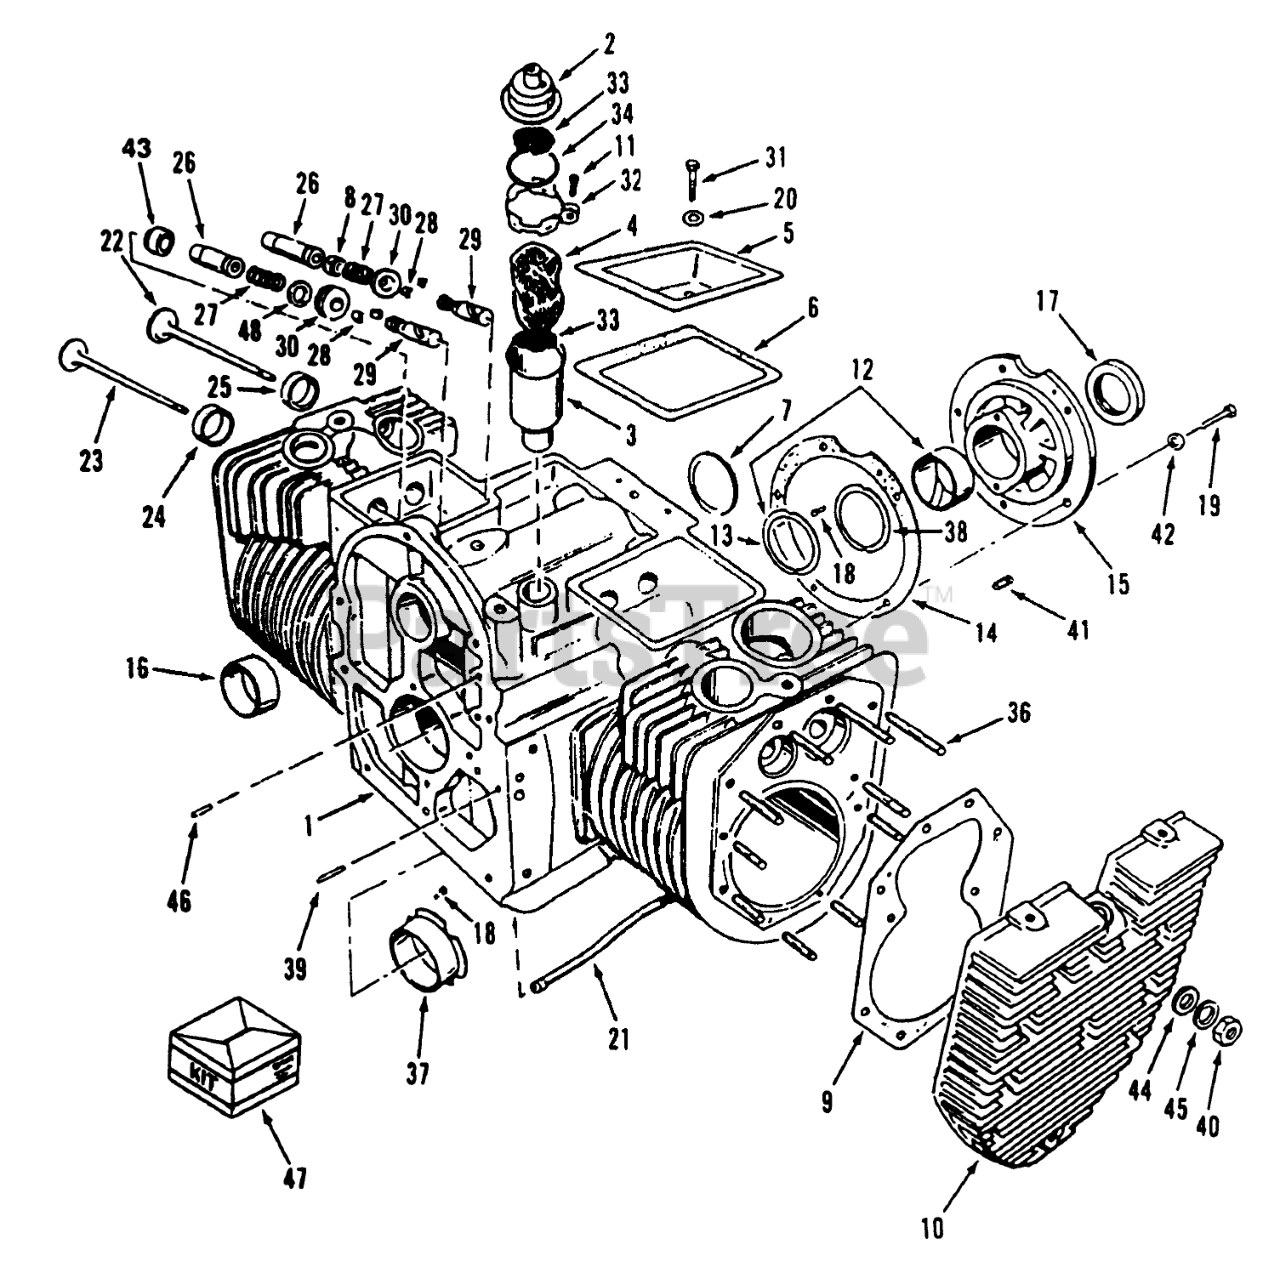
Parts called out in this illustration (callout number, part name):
1	Block-Short 24 HP. Spec. D Engine (Incl. Items #3, 7, 13-16, 18, 21, 24-26, 30, 36, 38, & 39
2	BREATHER-CAP AND VALVE
3	TUBE-BREATHER
4	FILTER
5	COVER-VALVE COMPARTMENT
6	GASKET-VALVE COVER
7	Plug
8	SUPPORT-AIR CLEANER
9	GASKET-CYLINDER HEAD
10	HEAD-CYLINDER
11	SCREW-TAPPING, ROUND HEAD
12	BEARING KIT (STANDARD SLEEVE)
13	Thrust Washer
14	GASKET
15	Plate-Bearing
16	SLEEVE-BEARING
17	Oil Seal
18	PIN-DRIVE
19	HEX HD CAPSCREW
20	Washer
21	TUBE-OIL, CRANKCASE
22	Intake Valve
23	Exhaust Valve
24	INSERT
25	Insert-Intake Seat STD
26	GUIDE-VALVE, EXHAUST
27	Spring-Valve
28	LOCK-VALVE SPRING
29	TAPPET
30	Rotator-Valve
31	SCREW - CAP HEX HEAD
32	Clamp
33	SCREEN-BREATHER TUBE
34	SEAL - O-RING
36	Mtg. Stud-Cylinder Hd (Install 4 Bottom Holes LH, RH Hd)
37	KIT-BEARING, SLEEVE
38	Shim 0.005"
39	Pin
40	NUT-HEX
41	Screw
42	Washer
43	Cap-Exhaust Valve
44	Washer
45	WASHER-LOCK, COMPRESS
46	Plug
47	KIT-GASKET CARB REM
48	WASHER
